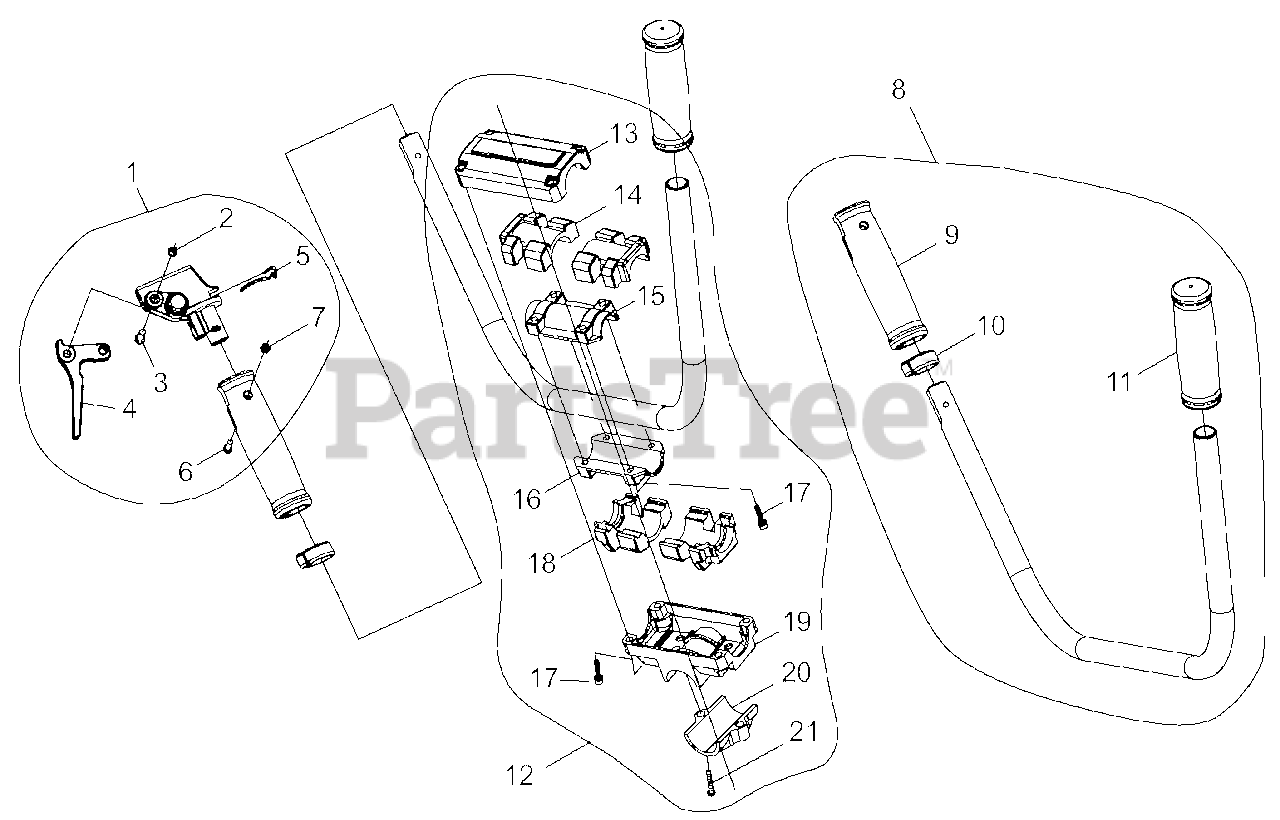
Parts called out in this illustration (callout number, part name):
1	THROTTLE CONTROL ASSY
2	LOCKNUT - 5
3	BOLT
4	TRIGGER, THROTTLE
5	STOP, THROTTLE
6	BOLT - 4X24
7	NUT - 4 -- NYLON
8	HANDLE ASSY
9	GRIP - RIGHT
10	HOLDER, CABLE
11	GRIP - LEFT
12	HANDLE BRACKET KIT
13	BRACKET, HANDLE - UPPER
14	CUSHION - UPPER
15	CLAMP - UPPER
16	CLAMP - LOWER
17	SCREW - 5X25
18	CUSHION - LOWER
19	BRACKET, HANDLE - LOWER
20	BRACKET, MOUNTING
21	SCREW - 6X25
